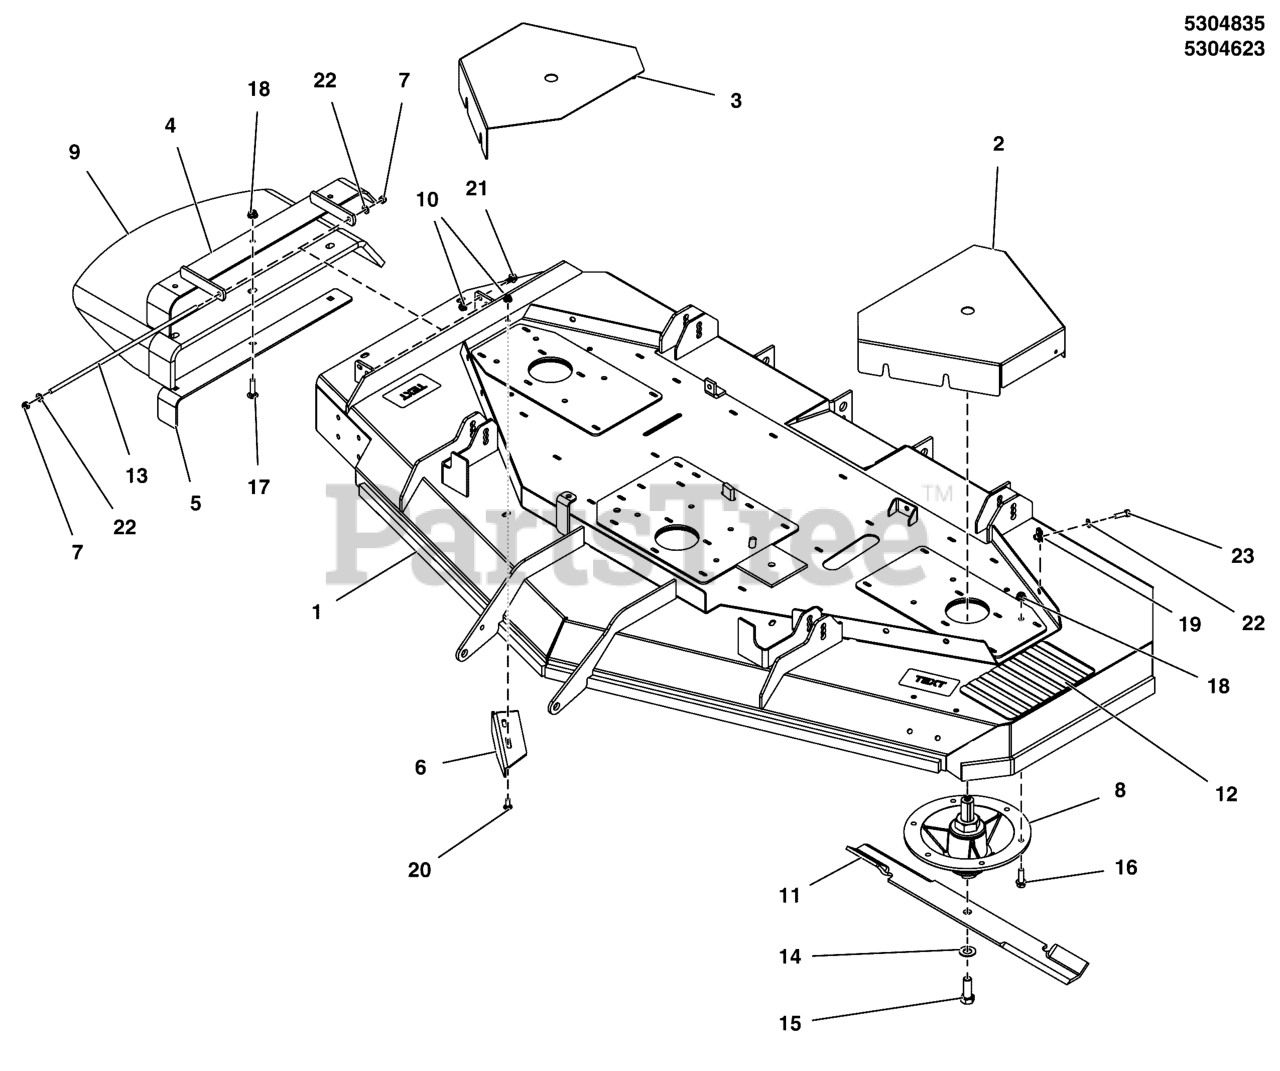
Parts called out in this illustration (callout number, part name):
1	DECK SHELL W/DECALS, 72, 200XT (5415368D)
1	DECK SHELL W/DECALS,72,S200XT(5417032D)
2	GUARD, MOWER DECK, IS3200-72, LH - RED
3	GUARD, MOWER DECK, IS3200-72, RH - RED
5	SUPPORT, DISCHARGE CHUTE - BLK
6	PLATE, DEFLECTOR, 72 - BLK
7	NUT, 5/16-24 HEX NYLON LOCK
8	SPINDLE ASSEMBLY
9	CHUTE, RUBBER DISCHARGE (5104442)
10	NUT, 5/16-18 HEX NYLOCK FLANGE NUT
11	BLADE, 25 X 25 X 2.50, HIGH LIFT (SET OF 3)
12	SAFETY WALK, 9.75 X 6.00
13	ROD, MOUNT, CHUTE, 61, CZ
14	WASHER, BLADE BOLT, 9/16" F436, CZ
15	BOLT, 5/8-11 X 1-3/4 GD8
16	BOLT, 3/8-16 X 1-1/4, FLANGE, GD 5, CZ
17	BOLT, 3/8-16 X 1-1/2, CARRIAGE, GD5, CZ
18	NUT, 3/8 - 16 HEX NYLOCK FLANGE
19	BODY CLIP, 5/16-18-7GA MATERIAL
20	BOLT, 5/16-18 X 3/4, CARRIAGE, GD5, CZ
21	BOLT, 5/16-18 X 3/4 GD5
22	WASHER, 5/16" SAE
23	BOLT, 5/16-18 X 1-1/4" GD5 YZ
